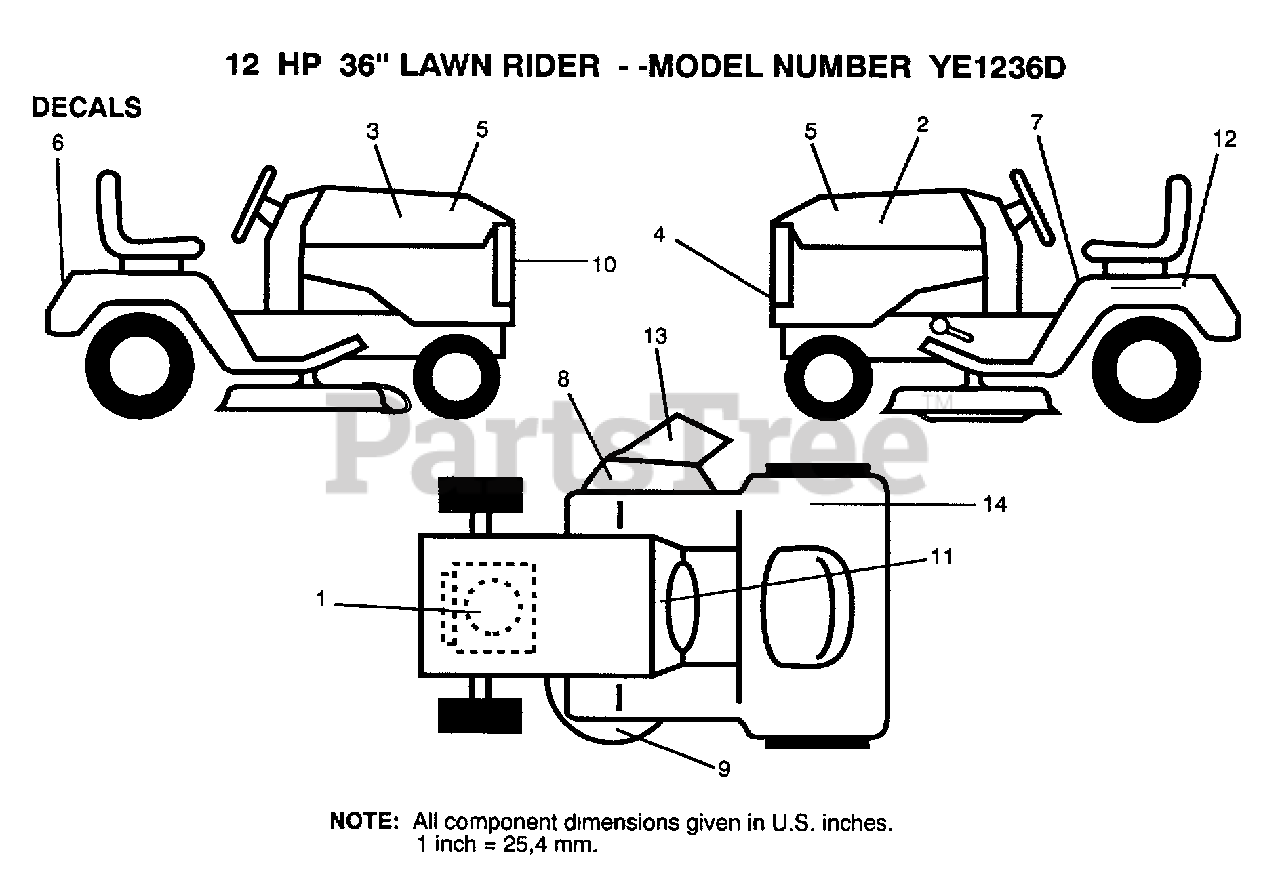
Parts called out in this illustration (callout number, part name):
1	DECAL.ENG.271967
4	GRILL DECAL
7	DECAL CAUTION
8	DECAL WARNING
9	DECAL YT
10	"DECAL,LIGHT BOX"
12	DECAL
13	DECAL WARNING
